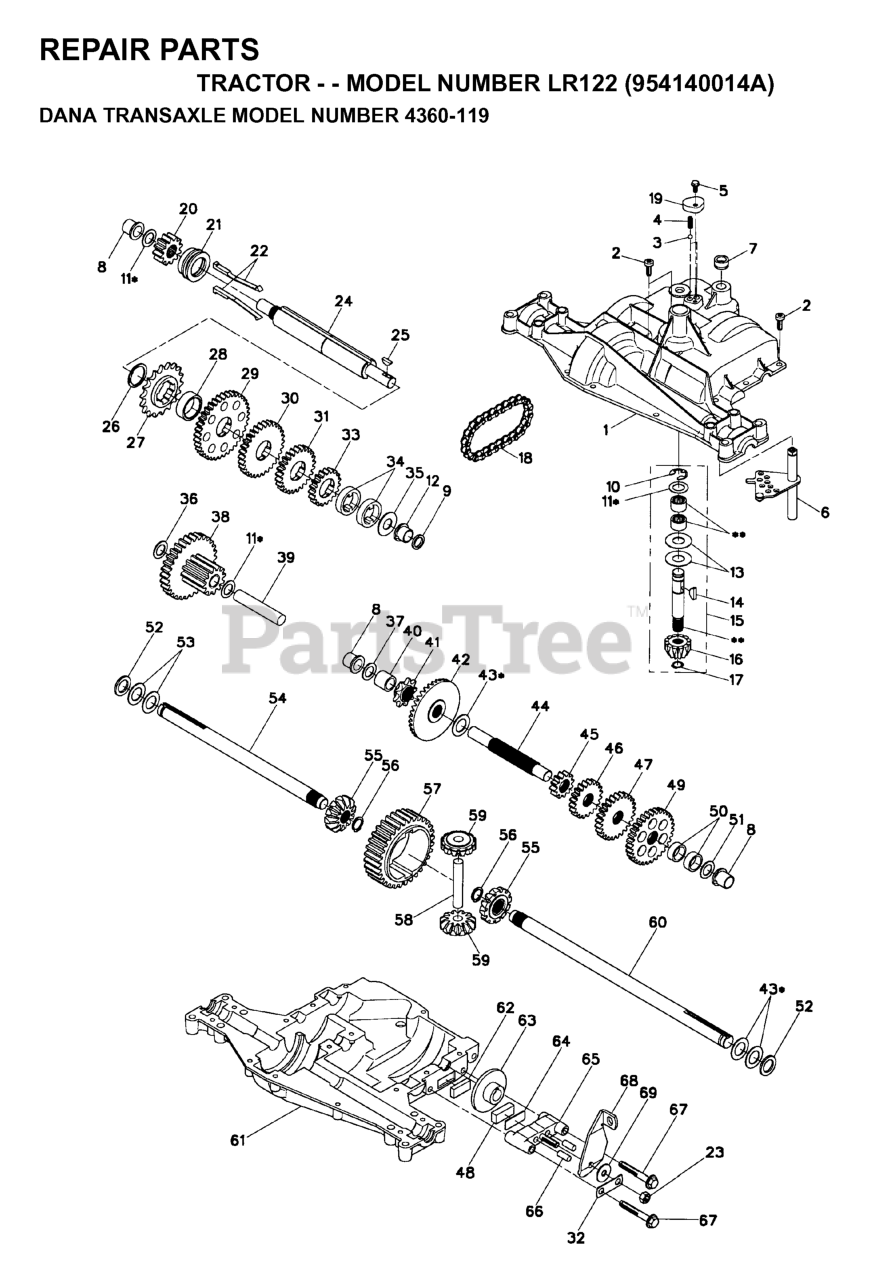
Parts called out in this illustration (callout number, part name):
2	RETAINING RING LT
4	KEY STD (1373) DANA
5	LOCKNUT
6	RP BOLT 5/16-18 X3/4 ZN/YEL GR
7	STRAP,TORQUE
8	SCREW.THDROL.5/16-18X3/4.TTY
9	SPRING,BRAKE RETURN
11	SQUARE KEY
15	WASHER
16	SUPT, HDLE SHT LH
17	LINK,SHIFT
18	BOLT 1/4-28X3/4
19	LOCKWASHER
22	WASH-SHFT PLT LT
23	KNOB T (1/2-HOLE)
24	ROD, SHIFT
25	PIN COTTER
26	LOCKNUT
28	SPRING.EXTENSION
29	SUPPORT HANDLE SHAFT RH
36	SCREW
